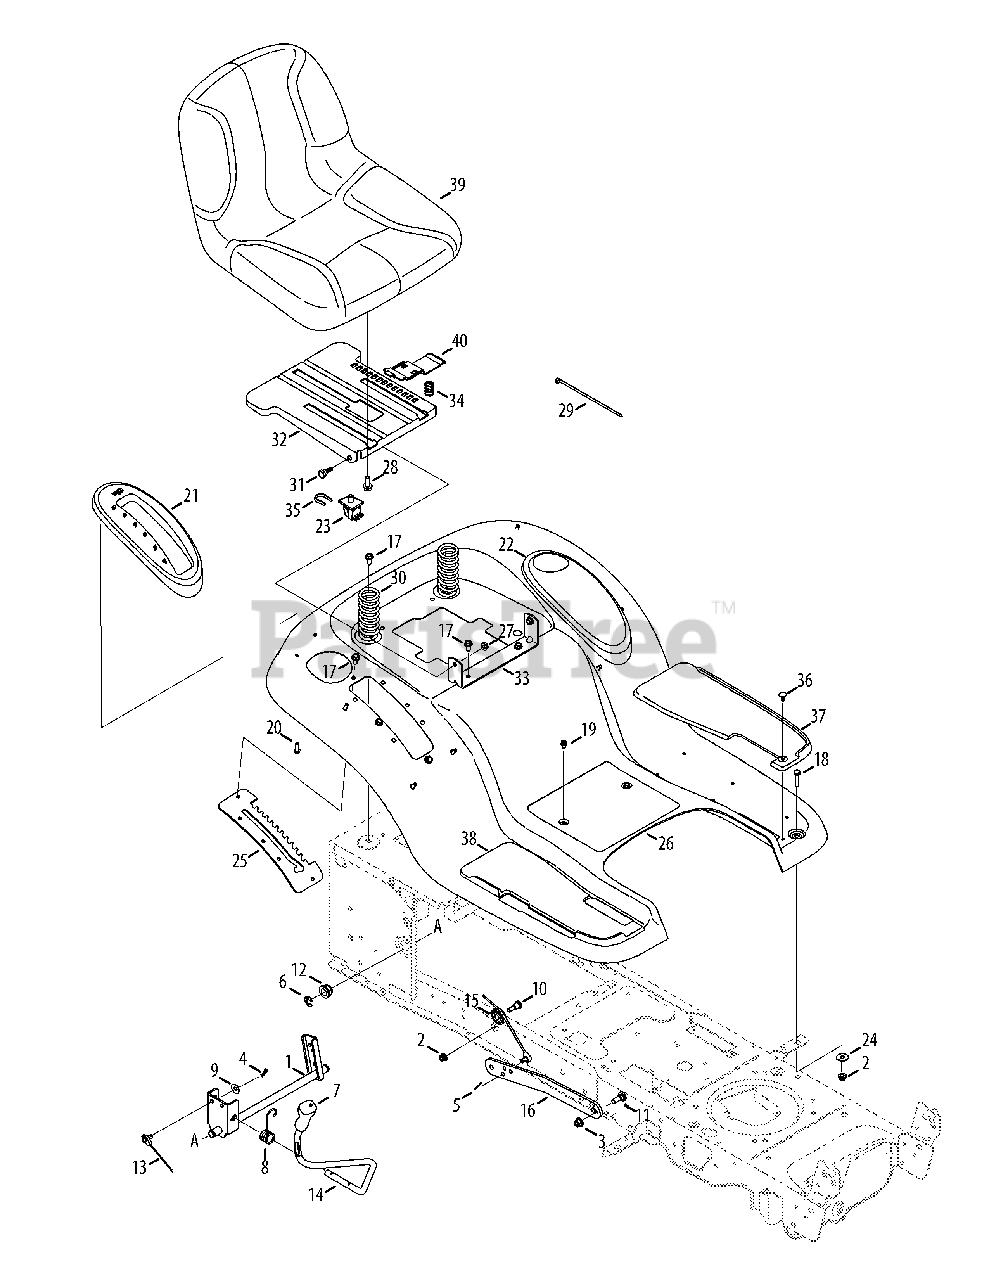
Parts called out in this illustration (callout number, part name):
1	Shaft Ass’y, Lift
2	Nut, Flange Lock, 5/16-18, Grf
3	Nut, Flange Lock, 3/8-16, Grf
4	Pin, Cotter, .072 Dia. x 1.13
5	Bow-Tie Cotter Pin, 42"
6	Ring, E Type, .625 Dia. Shaft
7	Grip, Handle, 1/2
8	Spring, Torsion
9	Washer, Spring, .401 x .870 x .063
10	Screw, Shoulder, .437 x .470, 5/16-18
11	Shoulder Bolt, .625 x .175 x 3/8-16, 42"
12	Bearing, Hex Flange
13	Cable, Lift, 16.16
14	Handle, Lift,
15	Pulley, Roller, Cable
16	Lift Arm, RH, 42"
16	Lift Arm, LH, 42"
17	Screw, Self-tapping, 5/16-18, .750,
18	Taptite Screw, 5/16-18:.750
19	Screw, Self-tapping, 1/4-20, 0.500,
20	Screw, HL, 1/4-15, 0.750,
21	Cover, Lift Lever
22	Cover w/ Cup Holder
23	Switch, Seat
24	Washer, Flat .344 x 1.00 x .063
25	Bracket, Lift, Man PTO, 6 Pos
27	Nut, Flange Lock, 5/16-18, Gr5, Sd Lk
28	Hex Head Flange Bolt, 3/8-16 x .875
29	Cable, Tie, 3/16 x .05 x 7.4
30	Spring, Comprs, 1.50 x 3.90 x .200
31	Screw, Shoulder, .437 x .268, 5/16-18
32	Bracket, Mounting, Seat
33	Bracket, Pivot, Seat
34	Comp. Spring, .68 x 1.065 x .055
35	Clip, Retaining, Switch
36	Clip, Ratchet, .250 Dia
37	Pad, Foot, LH
38	Pad, Foot, RH
39	Seat, Med Back, Black
40	Seat Adjustment Lever
